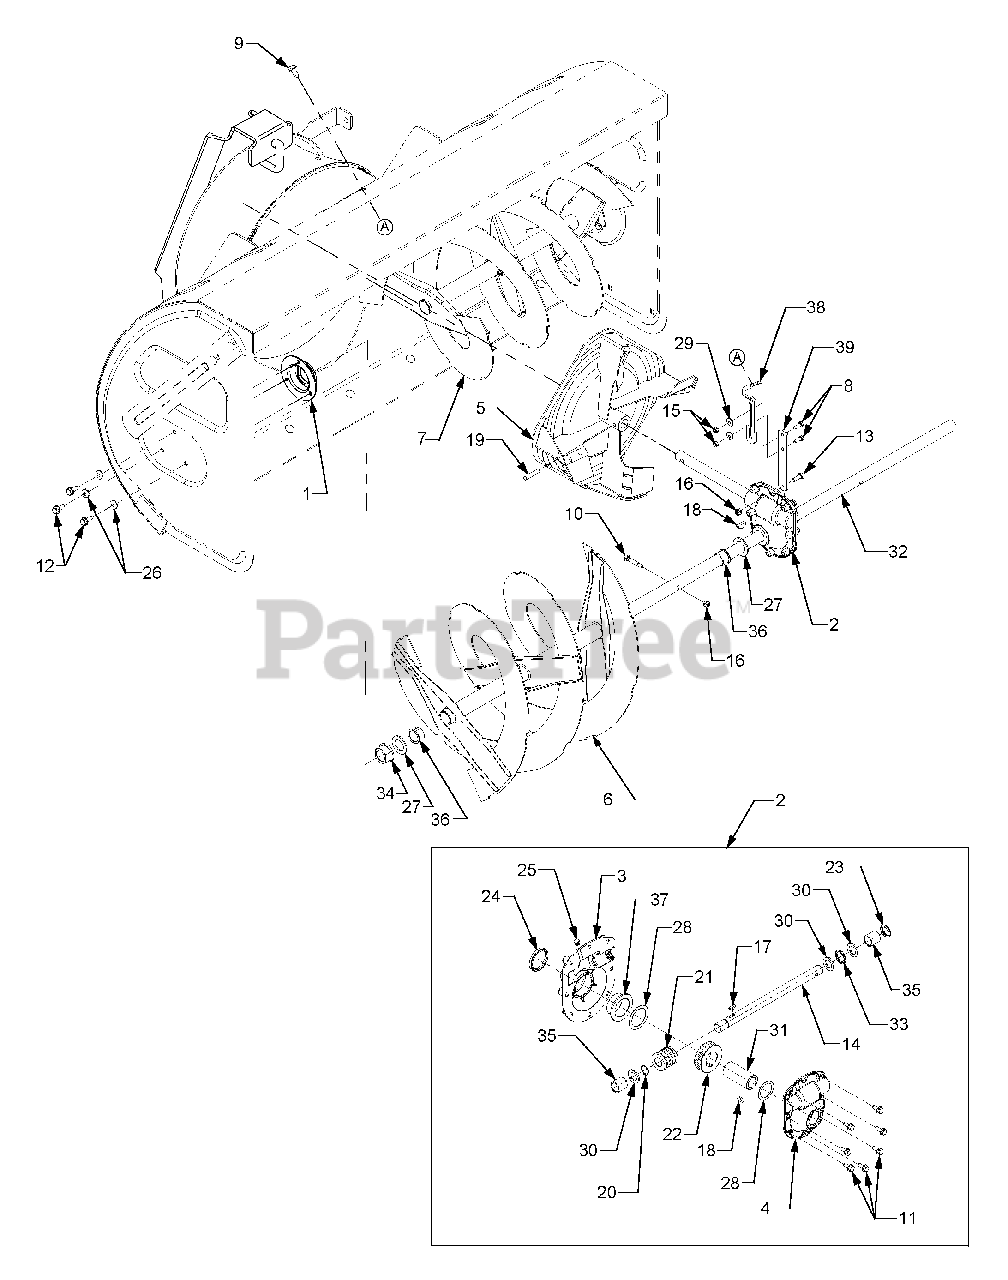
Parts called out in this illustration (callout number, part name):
1	Housing, Bearing
2	Auger Gear Box Assembly
3	Housing, Gear - RH
4	Housing, Gear - LH
5	Impellar Assembly
6	Spiral Assembly - RH
7	Spiral Assembly - LH
8	Screw, Hex Cap, 1/4-28 x .75 GR5
9	Screw, Hex Wash. Hd. Tapp 5/16-12 x .75
10	Bolt, Shear, 5/16-18 x 1.75
11	Screw, Hex Wash. Hd. Tapp 5/16-18 x .75
12	Screw, Hex Tap, 5/16-18 x .625
13	Screw, Hex Cap, 5/16-18 x .875 GR5
14	Shaft, Input
15	Nut, Hex, 1/4-28 GR5
16	Nut, Hex Insert Lock, 5/16-18
17	Key, Hi Pro, 3/16 x 3/4
18	Key, Woodruff, 1/4 x 3/4
19	Pin, Spirol, 5/16 x 1.75
20	Ring, Snap, .875 Shaft
21	Gear, Worm
22	Gear, Worm
23	Seal, Oil
24	Seal, Oil
25	Plug, 1/4 x .437
26	Washer, Bell, .340 x .872 x .06
27	Washer, Flat, 1.0 x 1.75 x .1
28	Washer, Flat, 1.5 x 2.0 x .3
29	Washer, Bell, .265 x .75 x .062
30	Washer, Flat, .88 x 1.4 x .125
31	Shaft, Worm Gear
32	Shaft, Spiral Axle
33	Bearing, Thrust
34	Bearing, Flange w/Flats
35	Bearing, Sleeve
36	Bushing, Flange
37	Bearing, Flange
38	Bracket, Gear Housing Support
39	Plate, Gear Housing Support
